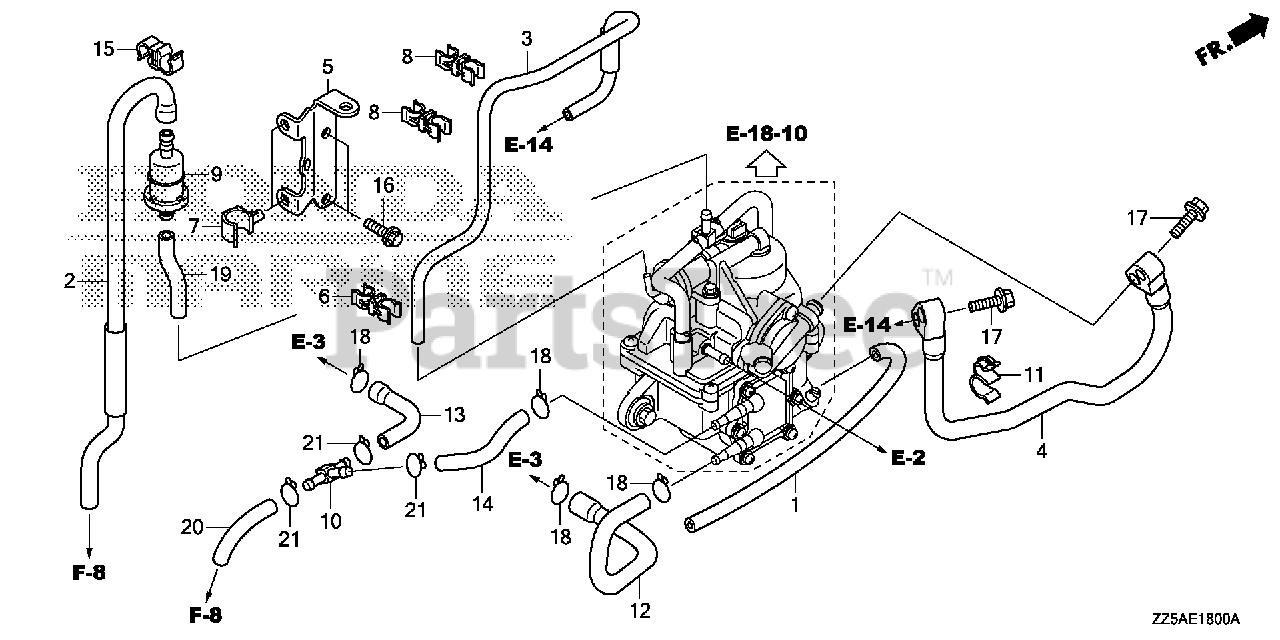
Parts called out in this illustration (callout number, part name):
1	TUBE, DRAIN
2	TUBE, AIR VENT
3	TUBE, PRESSURE REGULATOR
4	HOSE, FUEL
5	BRACKET A, TUBE CLAMP
6	CLAMP, AIR VENT TUBE
7	CLAMP B, FUEL TUBE
8	CLAMP D, FUEL TUBE
9	FILTER, FUEL
10	PIPE, THREE WAY JOINT
11	CLAMP, TUBE (7.5-11.5) (BLACK)
12	TUBE A, WATER
13	TUBE B, WATER
14	TUBE C, WATER
15	CLIP, R. BRAKE WIRE
16	BOLT, FLANGE (6X14) (CT200)
17	BOLT, FLANGE (6X25)
18	CLIP, TUBE (B10)
19	BULK HOSE, FUEL (5.5X3000) (5.3X35)
20	BULK HOSE, VACUUM (5X3000) (5X45)
21	CLIP, TUBE (B10)
